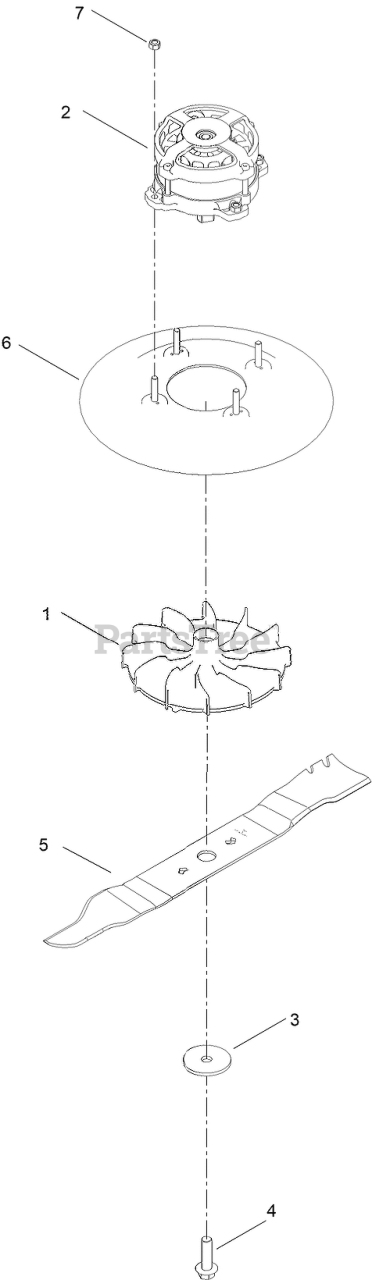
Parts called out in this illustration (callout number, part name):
1	BLADE CARRIER
2	MOTOR, BRUSHLESS, 60V, 850W
3	BLADE WASHER
4	BLADE BOLT
5	BLADE, MULCH, 43CM
6	BLADE COVER
7	NUT, NYLOC, M6X1
